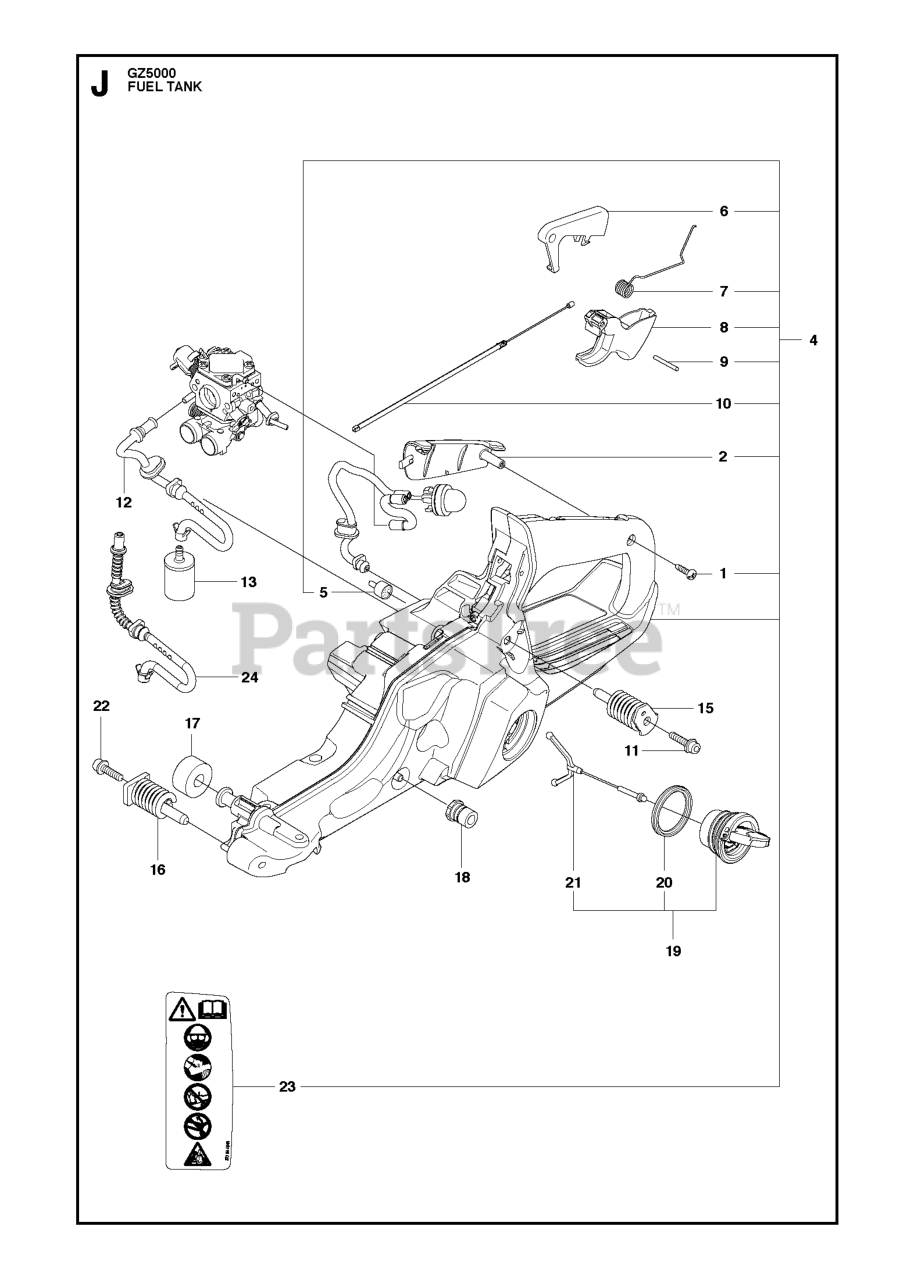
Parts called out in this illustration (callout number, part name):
1	SCREW CITXPANT
2	HANDLE INSERT
4	FUEL TANK ASSY
5	FUEL TANK VENT
6	THROTTLE LOCKOUT
8	THROTTLE
10	THROTTLE CABLE ASSY
11	SCREW ITXSCFT
12	FUEL HOSE
13	FUEL FILTER
15	ANTIVIBRATION ELEMENT WITH DEF
16	ANTIVIBRATION ELEMENT FRONT
17	DEFLECTION LIMITER
18	LATERAL SUPPORT
19	TANK CAP ASSY
24	FUEL HOSE
